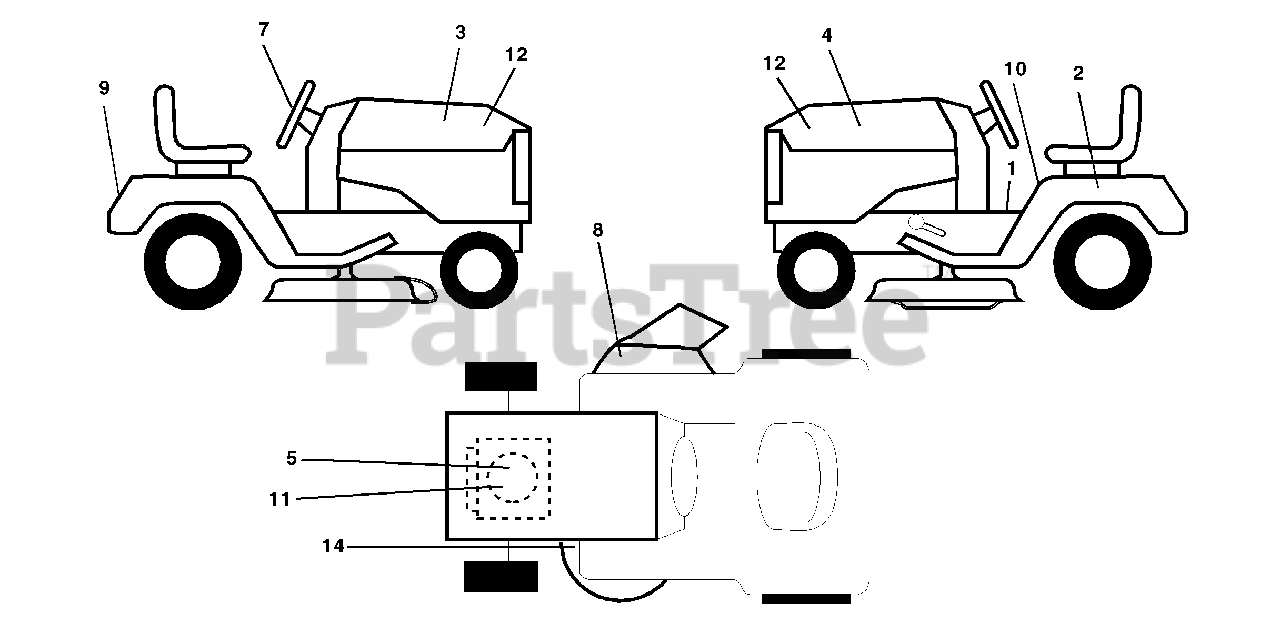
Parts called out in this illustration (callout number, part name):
1	Decal Oper. Step Thru E/F
2	Decal Battery
3	Decal Hood RH
4	Decal Hood LH
5	Decal HP Engine
7	Decal Wheel Steering
8	Decal Warning
9	Decal Fender Husq
10	Decal Fender Danger E/F
11	Decal Engine
12	Decal Hood Logo
14	Decal V-Belt Schematic
